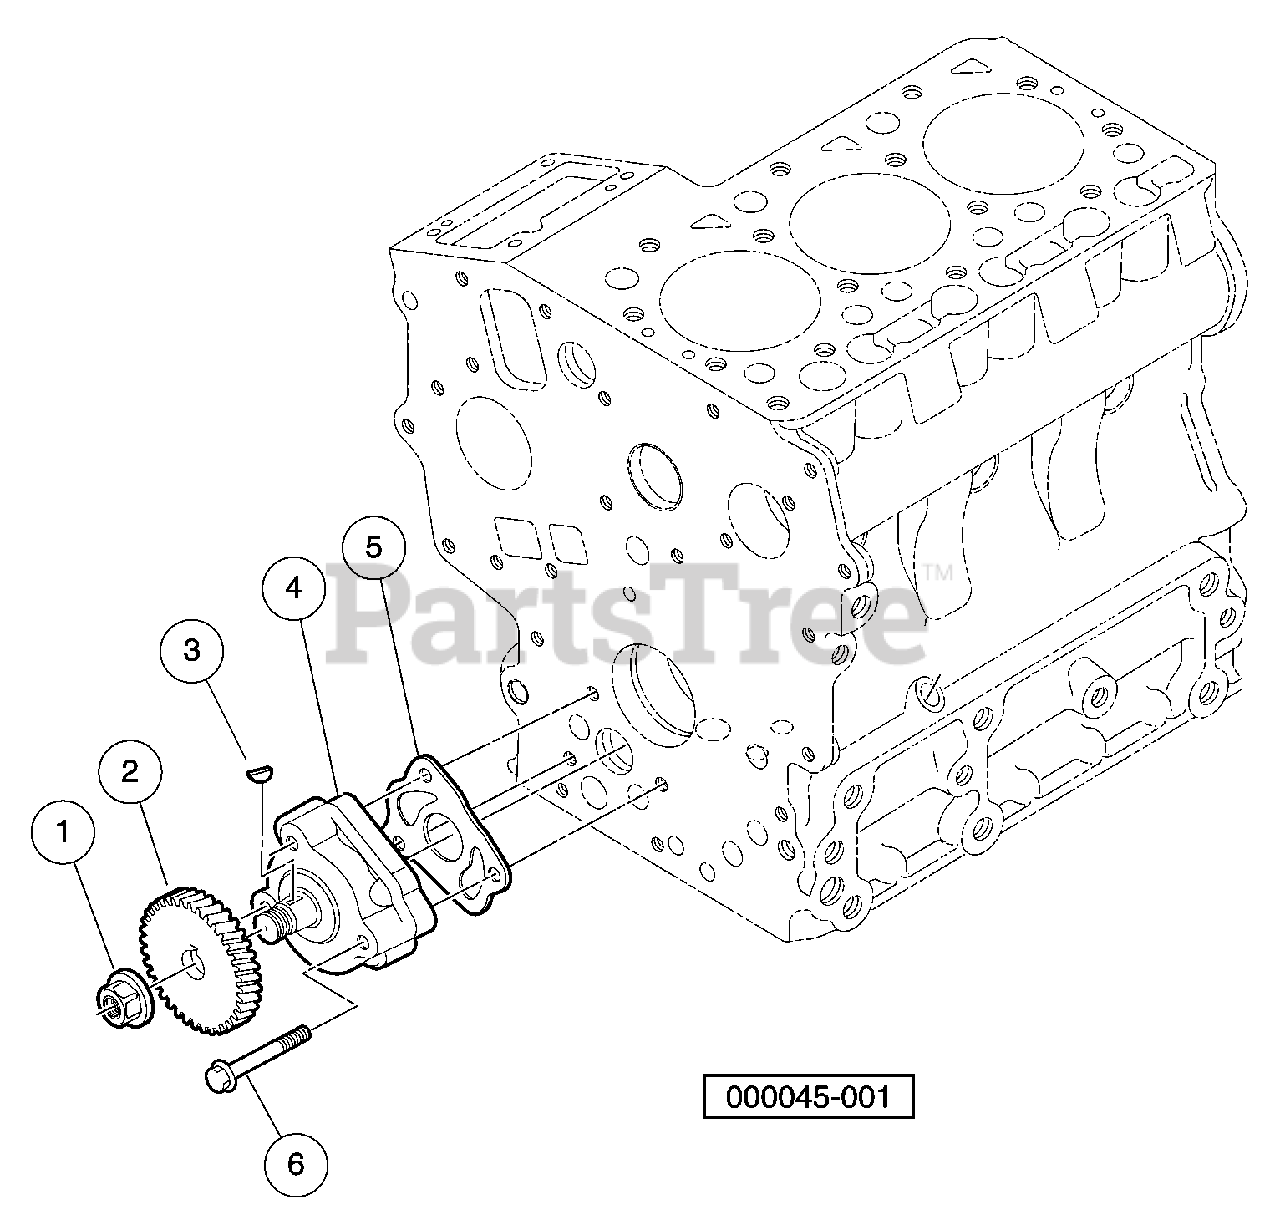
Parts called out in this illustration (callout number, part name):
1	Nut, Flange, D722 Oil Pump
2	Gear, Oil Pump Drive
3	Key, Feather, 8x4
4	Assy, Pump, Oil
5	Gasket, Oil Pump
6	Bolt, Oil Pump
